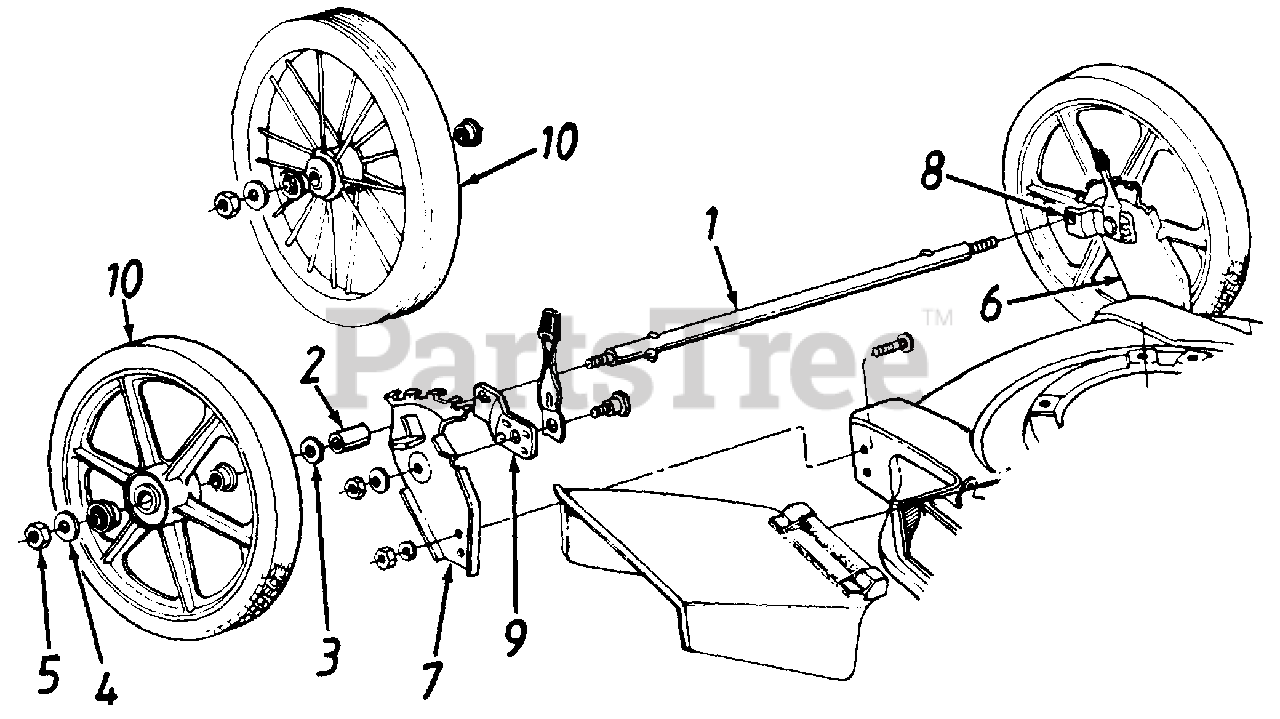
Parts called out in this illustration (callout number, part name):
1	Rear Axle .500 Dia. x 22.83
2	Spacer .550 I.D. x .755 O.D.
3	Wave Washer .510 I.D. x .750 O.D.
4	Flat Washer .406 I.D. x .810 O.D.
5	Hex Ins Top-L Jam Nut 3/8-16
9	Small Pivot Bar - RH
10	Rear Wheel Ass'y. 16" (Plastic)
